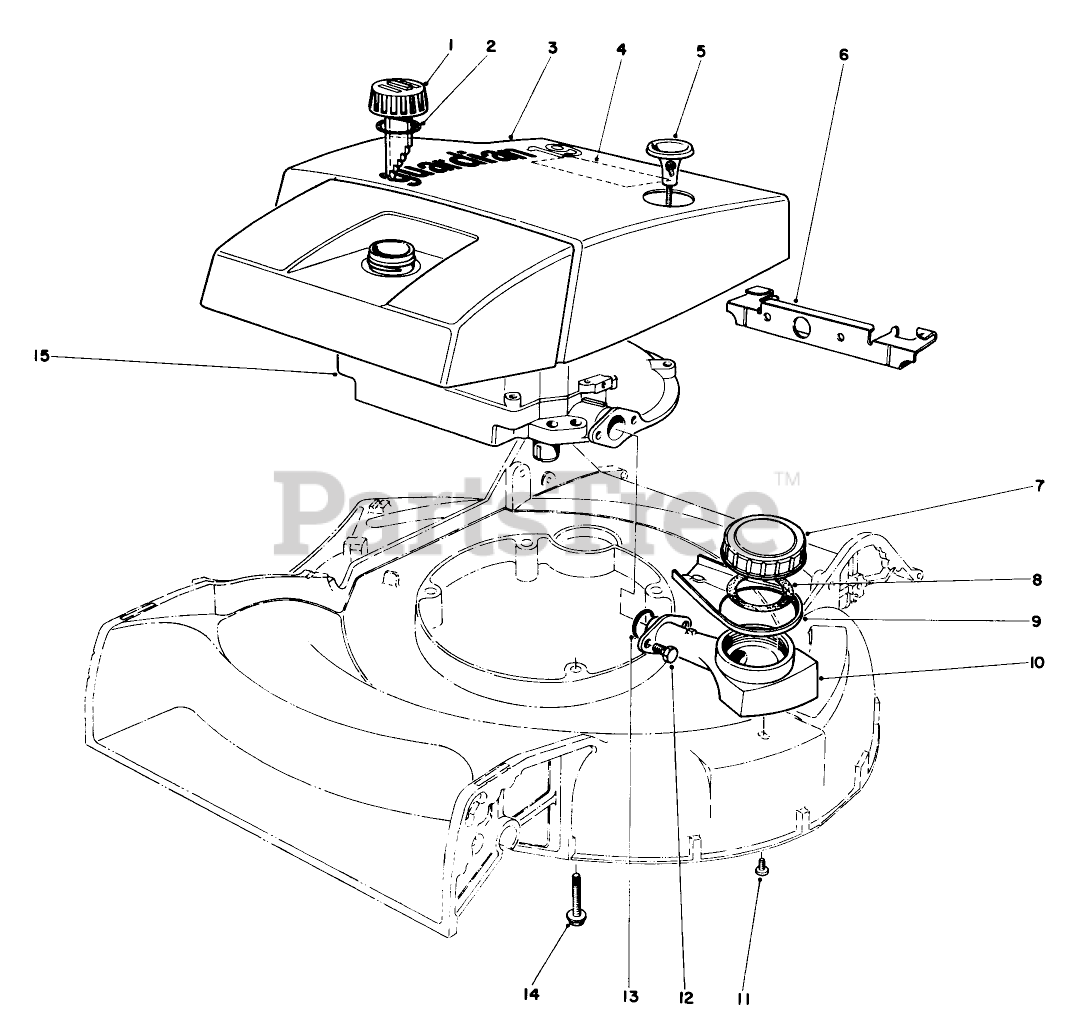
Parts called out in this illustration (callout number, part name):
1	Gas Cap (Incl. Ref. #2)
2	Gasket
3	Shroud
4	Decal-Maintenance
5	Rope Handle
6	Shroud Bracket
7	Oil Gauge Cap
8	VISUAL OILER GASKET
9	Spout
10	Oil Gauge
11	Screw
12	SCREW-HH
13	O RING
14	3/8-16 X 2-3/4 CAPSCR
15	Engine
